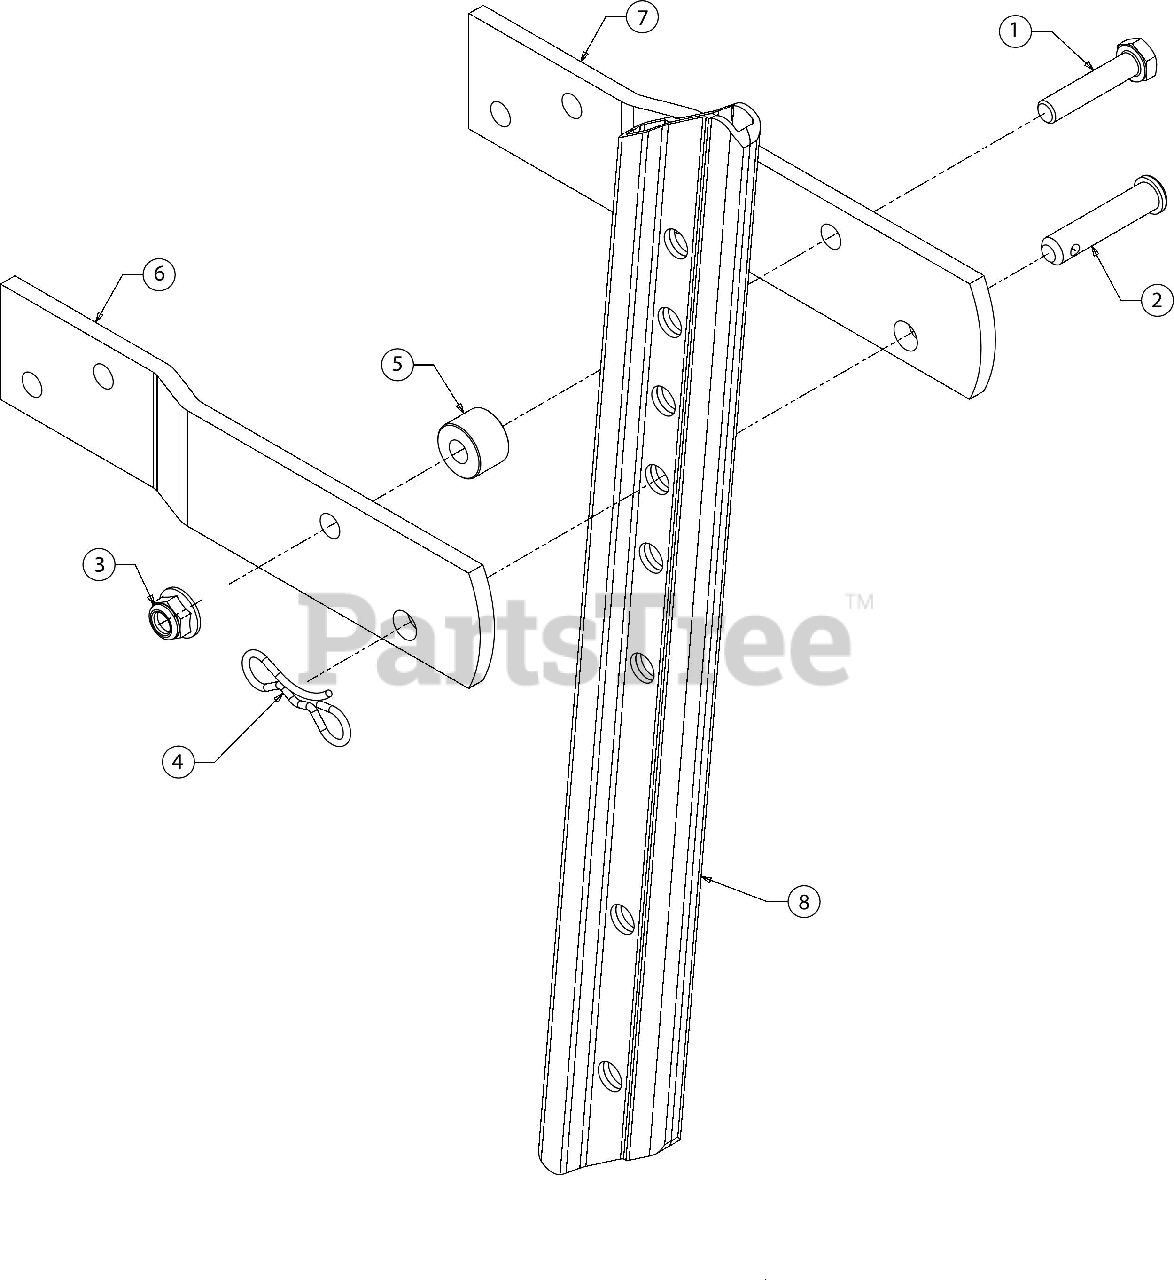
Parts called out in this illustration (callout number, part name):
1	SCREW 5/16-18 X 1.5 LG
2	CLEVIS PIN .375 X .1.75
3	FLANGE LOCK NUT 5/16-18
4	PIN:COTTER
5	SPACER
6	TAILPIECE BRACKET
7	TAILPIECE BRACKET
8	DEPTH BAR
